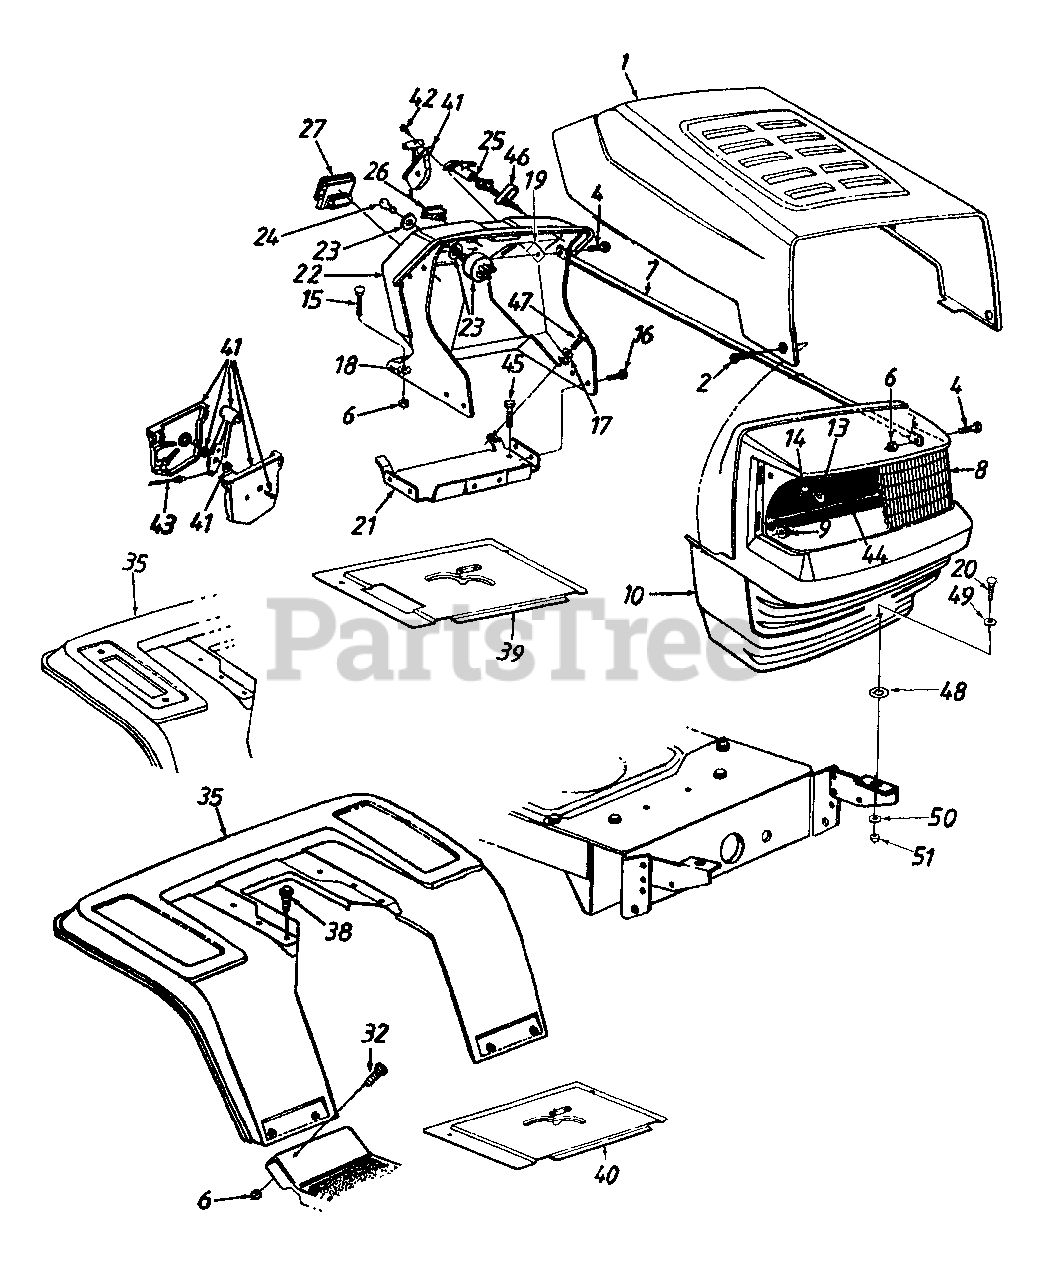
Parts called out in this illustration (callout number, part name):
4	Hex Bolt 1 /4-20 x .62" Lg.
6	Hex Sems Nut 1/4-20 Thd.
8	Headlight Lens (w/o Logo)
8	Headlight Lens (w/Logo)
9	Flange L-Nut 1/4-20 Thd.
10	Grille
14	Socket
15	Carriage Bolt 1/4-20 x .75" Lg.
16	Hex Washer Tap Scr. 1/4-20 x .5" Lg.
17	Fl-Wash. .281" I.D. x .73" O.D.
18	Bolt Retainer 1/4" I.D.
19	Speed Nut 1/4-20 Thd.
20	Hex Bolt 5/16-18 x .75" Lg.
21	Gas Tank Support Brkt.
22	Dash w/Ammeter Hole
22	Dash w/o Ammeter Hole
23	Ignition Switch
24	Ignition Key
25	Choke Control 23" Lg.
25	Choke Control 38" Lg.
25	Choke Control 20" Lg.
25	Choke Control 29" Lg.
26	Light Switch
27	Ammeter
32	Truss Mach. Scr. 1/4-20 x .5" Lg.
39	Shift Cover w/Cutout
40	Shift Cover
41	Throttle Box Ass'y.
42	Truss Mach. AB-Tap Scr.#10 x .5"
43	Throttle Control Wire 18.5" Lg.
43	Throttle Control Wire 35" Lg.
43	Throttle Control Wire 22" Lg.
44	Grille Reflector Label
45	Hex Washer Tap Scr.5/16-18 x .5" Lg.
46	Choke Retainer
47	Hex TT-Tap Scr. 1/4-20 x .75" Lg.
48	Speed Nut
49	Fl-Wash. .34" LID. x 1"Lg.
50	L-Wash. 5/16" I.D.
51	Hex Nut 5/16-18 Thd.
